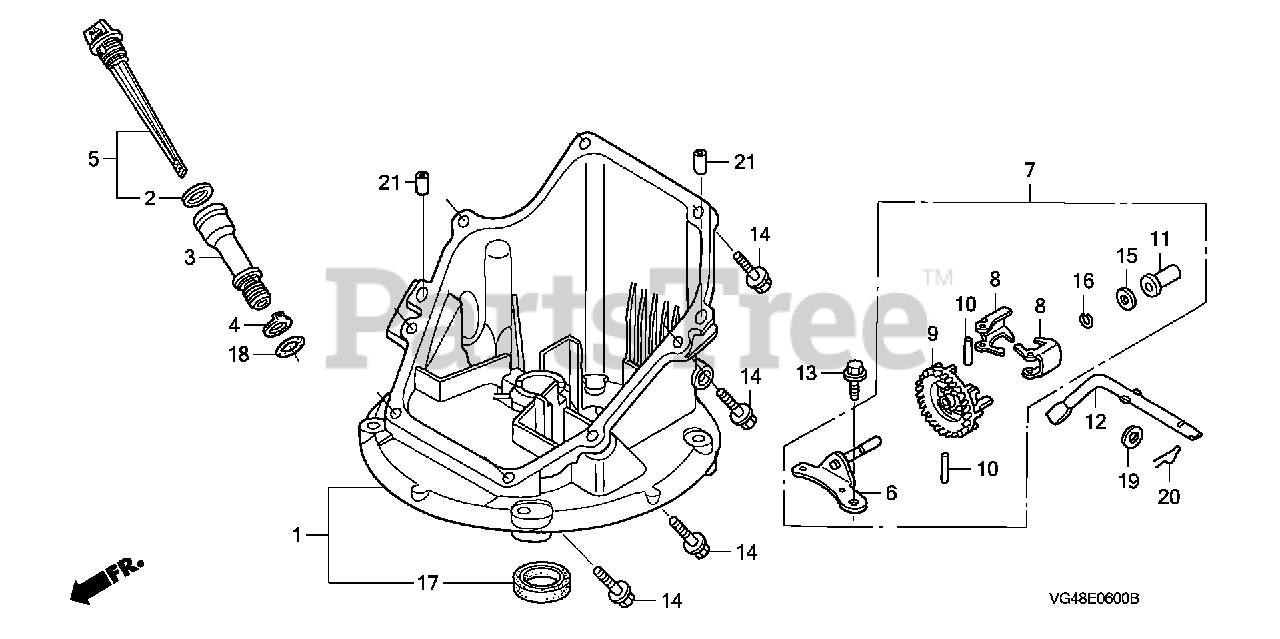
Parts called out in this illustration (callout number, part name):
1	PAN ASSY., OIL
2	GASKET, OIL FILLER CAP
3	EXTENSION, OIL FILLER
4	WASHER, EXTENSION LOCK
5	GAUGE ASSY., OIL LEVEL
6	SHAFT, GOVERNOR HOLDER
7	GOVERNOR ASSY.
8	WEIGHT, GOVERNOR
9	HOLDER, GOVERNOR WEIGHT
10	PIN, GOVERNOR WEIGHT
11	SLIDER, GOVERNOR
12	SHAFT, GOVERNOR ARM
13	BOLT, FLANGE (6X14) (CT200)
14	BOLT, FLANGE (6X25) (CT200)
15	WASHER, THRUST (6MM)
16	CLIP, GOVERNOR HOLDER
17	OIL SEAL (28X41.25X6)
18	O-RING (14.8X2.4) (ARAI)
19	WASHER, PLAIN (6MM)
20	PIN, LOCK (8MM)
21	PIN, DOWEL (8X20)
